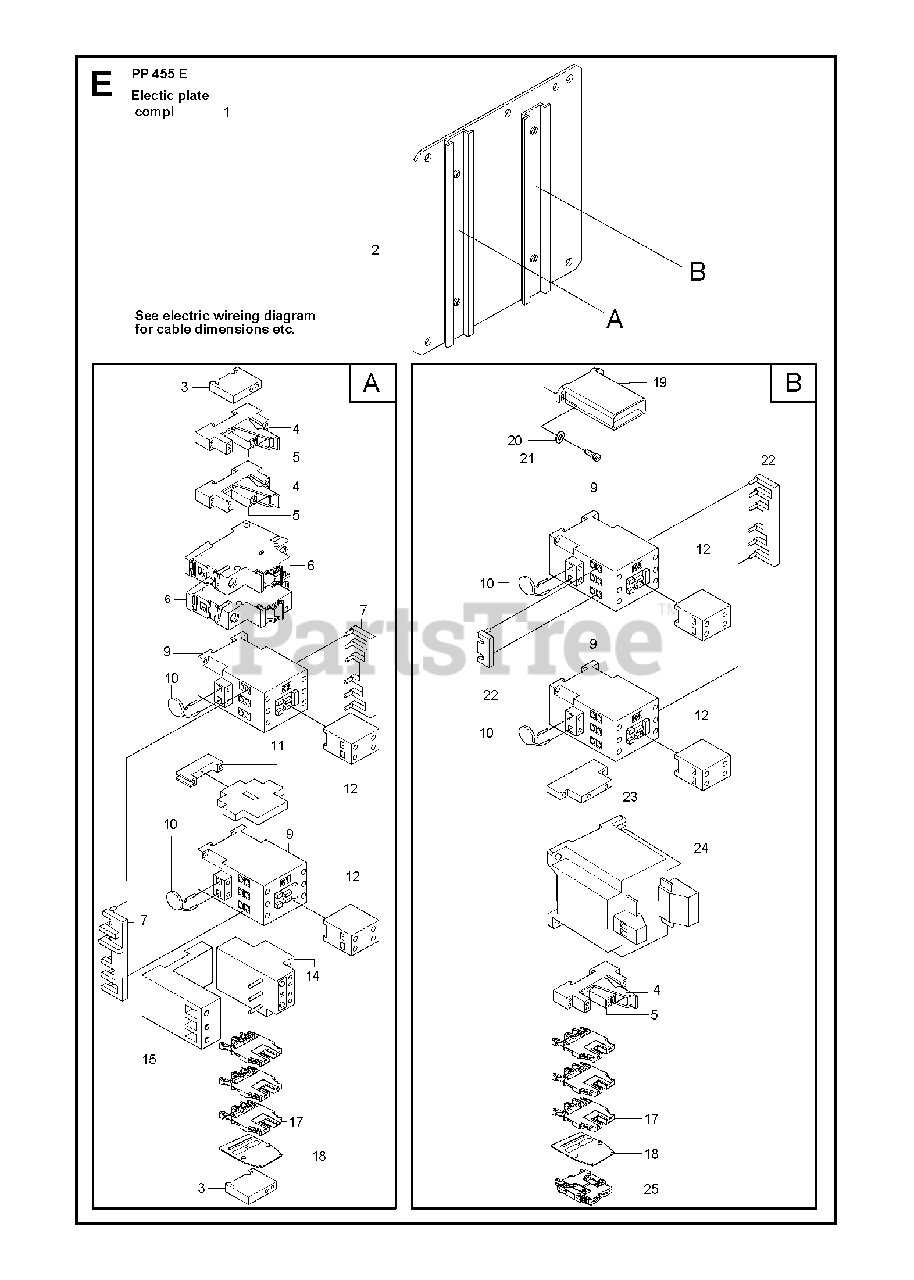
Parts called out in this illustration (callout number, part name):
1	ELECTRICAL SYSTEMUS 440V
1	EL. PLATE COMPL. 200V JAPANJAP 200V
1	EL. PLATE COMPL. 230/400V NONOR 230/400V
14	ENGINE PROTECTIONJAP 200V, NOR 230/400V, CAN 600V
14	RELAYEUR 400V, US 480V
15	ATTACHING BASEJAP 200V, CAN 600V
15	BASEEUR 400V, US 480V
19	DOUBLE PHASE SEQUENCE S400V
20	WASHER
24	TRANSFORMERNOT ON 200V, 230/400V
